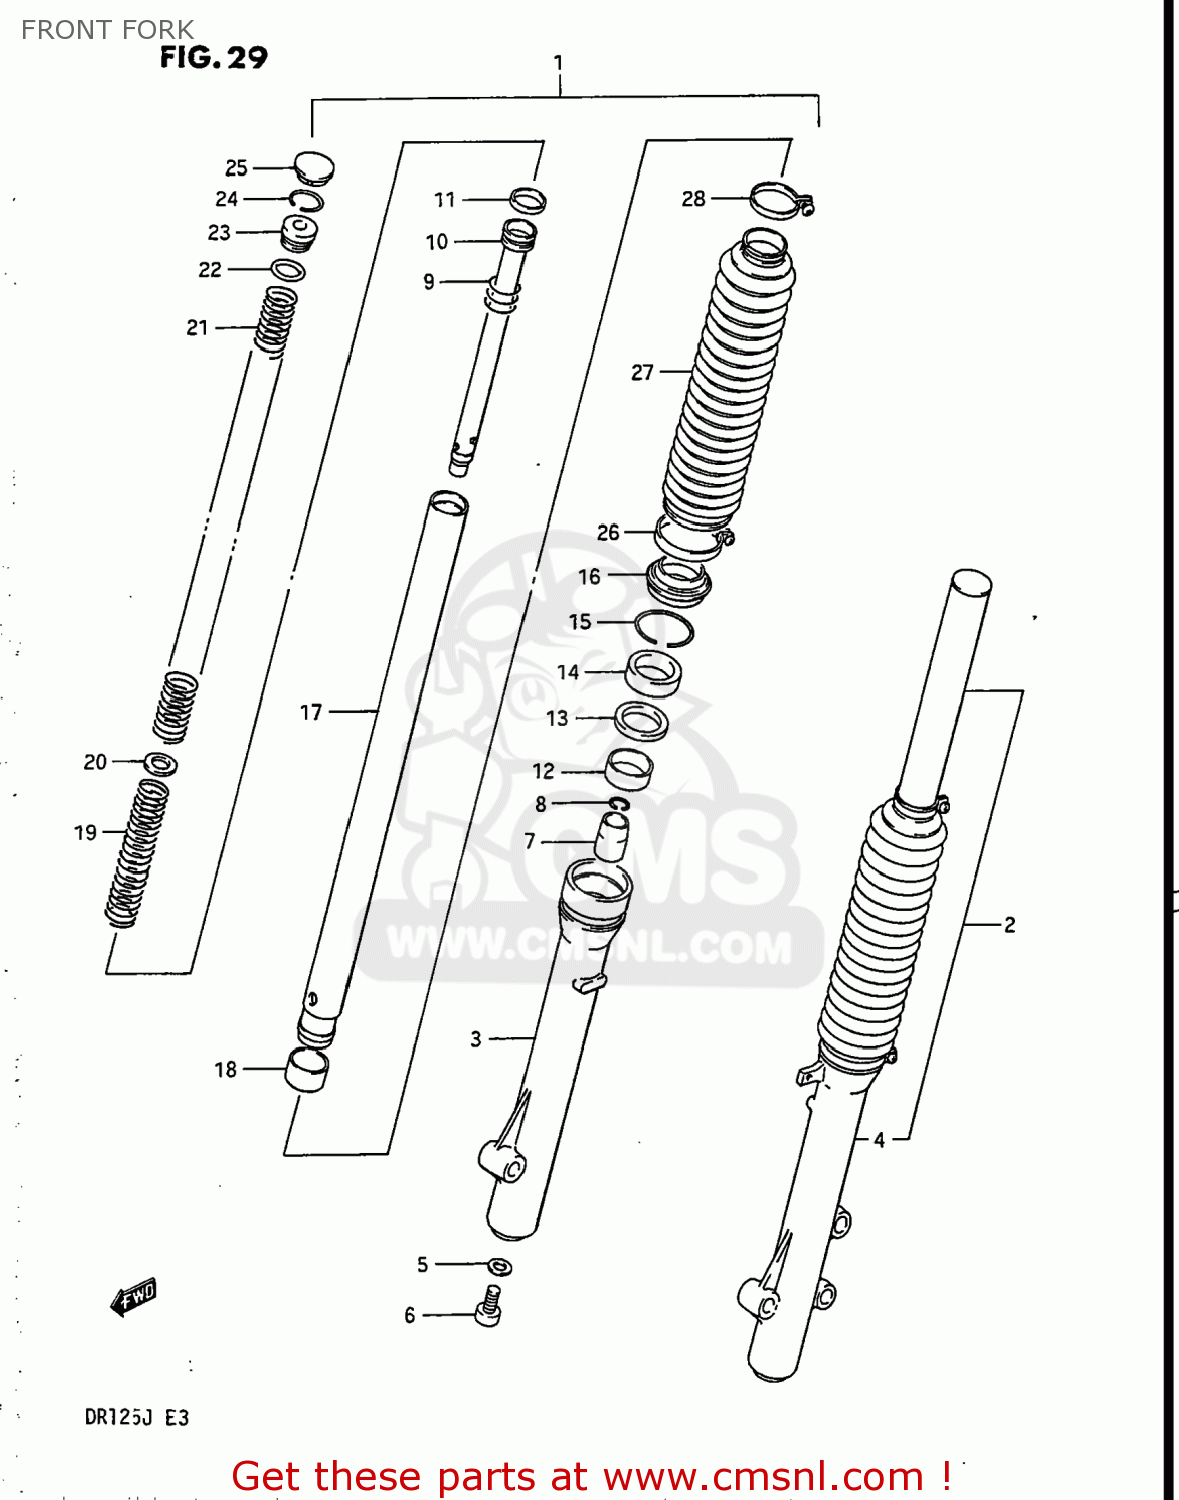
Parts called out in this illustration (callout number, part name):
1	DAMPER ASSEMBLY,RIGHT
2	DAMPER ASSEMBLY,LEFT
3	TUBE,OUTER,RIGHT
4	TUBE,OUTER,LEFT
5	GASKET (NAS)
6	BOLT(8X27)
7	PIECE,OIL LOCK
8	RING,STOPPER
9	SPRING,REBOUND
10	CYLINDER,FRONT FORK
11	RING,PISTON
12	BUSH,GUIDE
13	SPACER,SEAL
14	OIL SEAL,FRONT FORK
15	CIRCLIP,FORK OIL SEAL
16	SEAL,DUST
17	TUBE,INNER
18	PISTON
19	SPRING,LWR
20	SPRING,JOINT
21	SPRING,UPR
22	O RING
23	SPRING SEAT B
24	RING,STOPPER
25	CAP
26	BAND
27	BOOT
28	BAND
